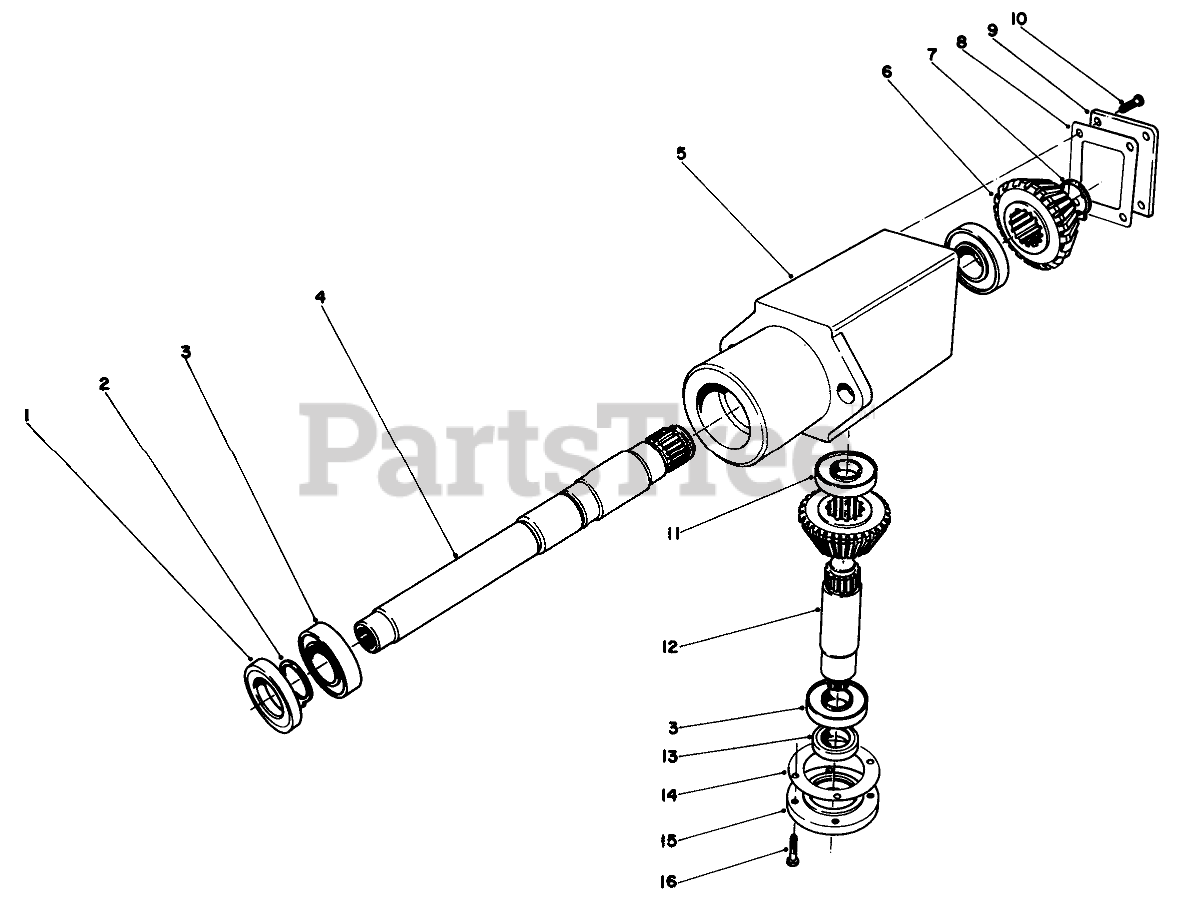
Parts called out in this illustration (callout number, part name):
1	Oil Seal
2	Ring-Snap
3	Bearing
4	Shaft, Output
5	Housing, Right Angle Drive
6	Bevel Gear
7	Ring-Snap
8	Gasket
9	Cover
10	BRACKET
11	Bearing
12	Shaft, Input
13	Oil Seal
14	Gasket
15	Cap & Seal Assembly (Incl. Ref. #13 & 16)
16	SCREW-HH
